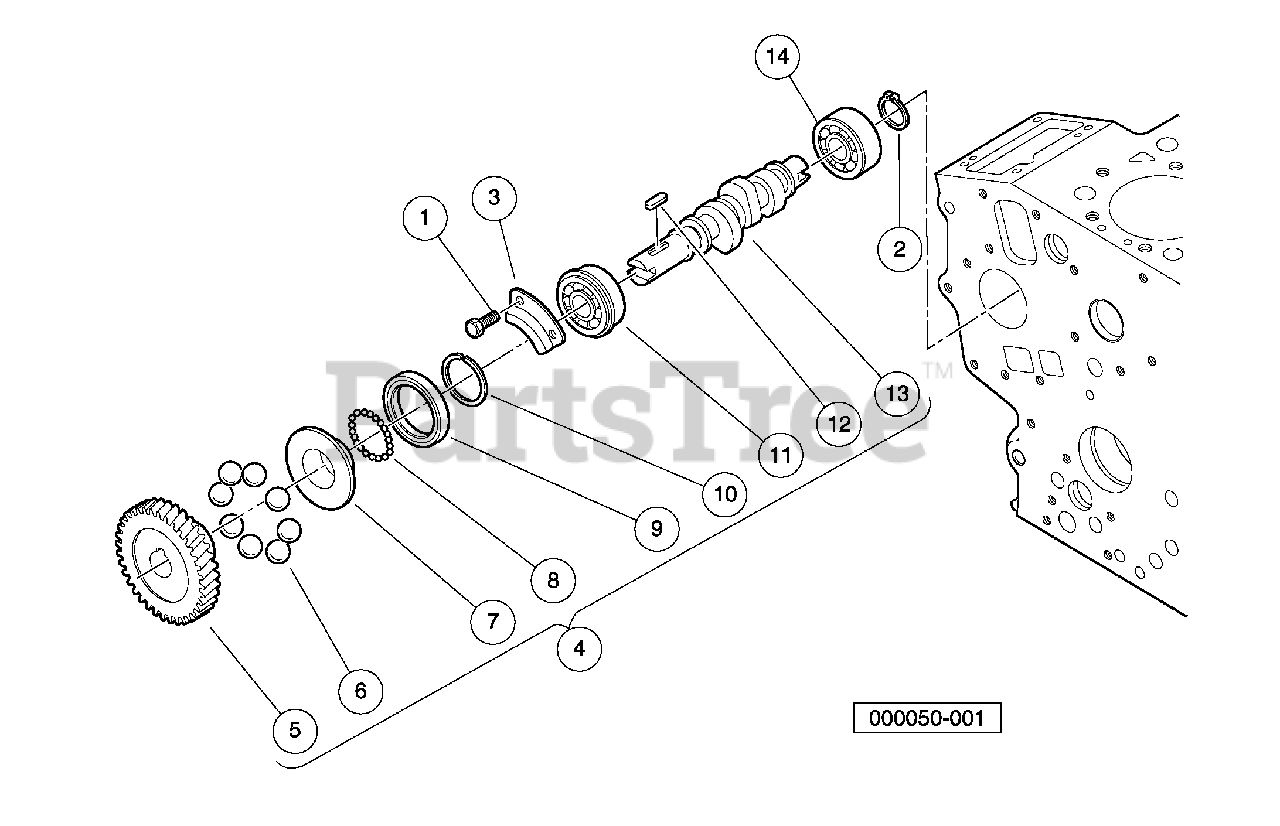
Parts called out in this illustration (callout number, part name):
1	Bolt, D722, Cam End
2	Circlip, External
3	Stopper, Fuel, C/shaft
4	Assy, Fuel Camshaft
5	Gear, Injection Pump
6	Ball, Injection Pump
7	Sleeve, Governor
8	Ball, Governor.
9	Case, Governor Ball
10	Circlip
11	Bearing, Ball
12	Key, Feather, Short Camshaft.
13	Camshaft, Fuel, Short
14	Bearing, Ball
